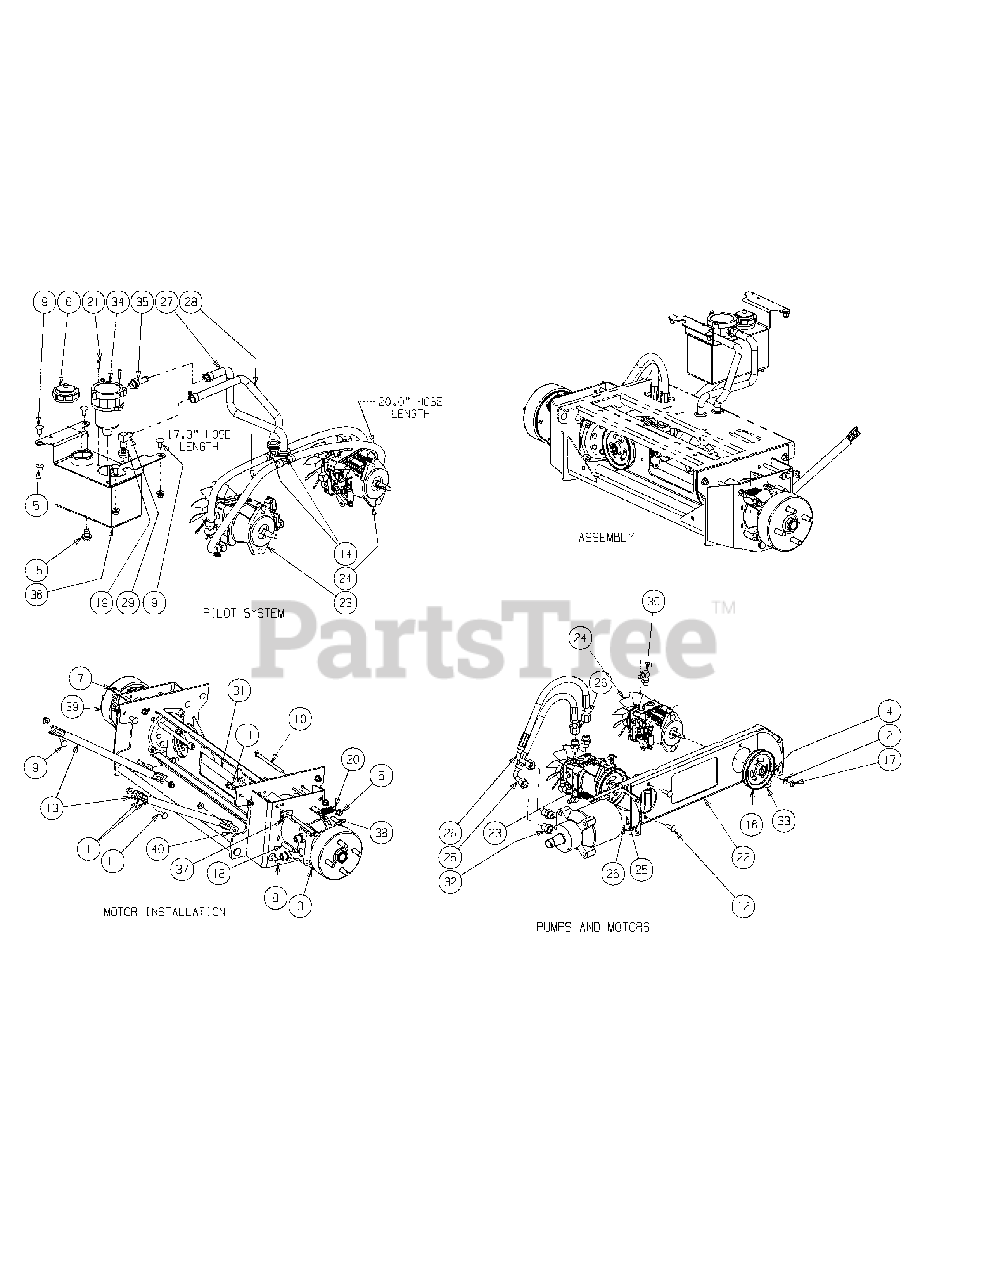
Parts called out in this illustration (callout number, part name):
1	Washer lock 3/8 zinc
2	Flat Washer, 3/8
3	Washer lock 3/8 zinc
4	Key, 3/16" x 7/8"
5	Flange Lock Hex Nut, 3/8-16
6	Cap, Hydro Oil Tank
7	Hex Cap Screw, 3/8-16 x 5.00
8	Hex Cap Screw, 3/8 -16 x 1.25
9	Carriage Bolt, 3/8-16 x .75 LG.
10	Carriage Bolt, 3/8-16 x 5.50
11	Carriage Bolt, 3/8-16 x 1
12	Carriage Screw, 3/8-16 x 1.25
13	Strut Frame
14	Grommet, .75 ID
15	Oil Pan Drain Plug w/ Seal
16	Hydro Pump Pulley
17	Hex Nut, 3/8-24
18	Socket Head Capscrew, 1/2-13; 6-1/2
19	Grommet Fitting, .54 ID x .78 OD
20	Spring Extension, .740 OD x 2.656
21	Socket Low Head Cap Screw, 1/4-20 x 0.75
22	Hydro Pump Mounting Bracket
23	Hydro Pump, BDP-12, LH
24	Hydro Pump, BDP-12, RH
25	Hose Assembly
26	Hose Assembly
27	Hose Assembly, Pilot includes:
27	Hose Clamp
27	Hose, .50 ID x .75 OD
28	Hose Assembly, Drain includes:
28	Hose Clamp
28	Hose, .50 ID x .75 OD
29	Fitting Elbow Spur, 5/8 x 1/2
30	Fitting Elbow, 9/16 x 1/2
31	Hydro Motor Frame Assembly
32	Adaptor Fitting, 8 x 10
33	Adaptor Fitting, 8 x 8
34	Hydraulic In-Tank Filter includes:
35	Fitting, 3/4 ORB x 1/2 Tube
36	Hydraulic Tank Assembly
37	Rear Cable Mounting Bracket
38	Hydro Motor, Left Hand Assembly w/ Brake & Drum
39	Hydro Motor, Right Hand Assembly w/ Brake & Drum
40	Spacer .406 ID x 1.0 OD
